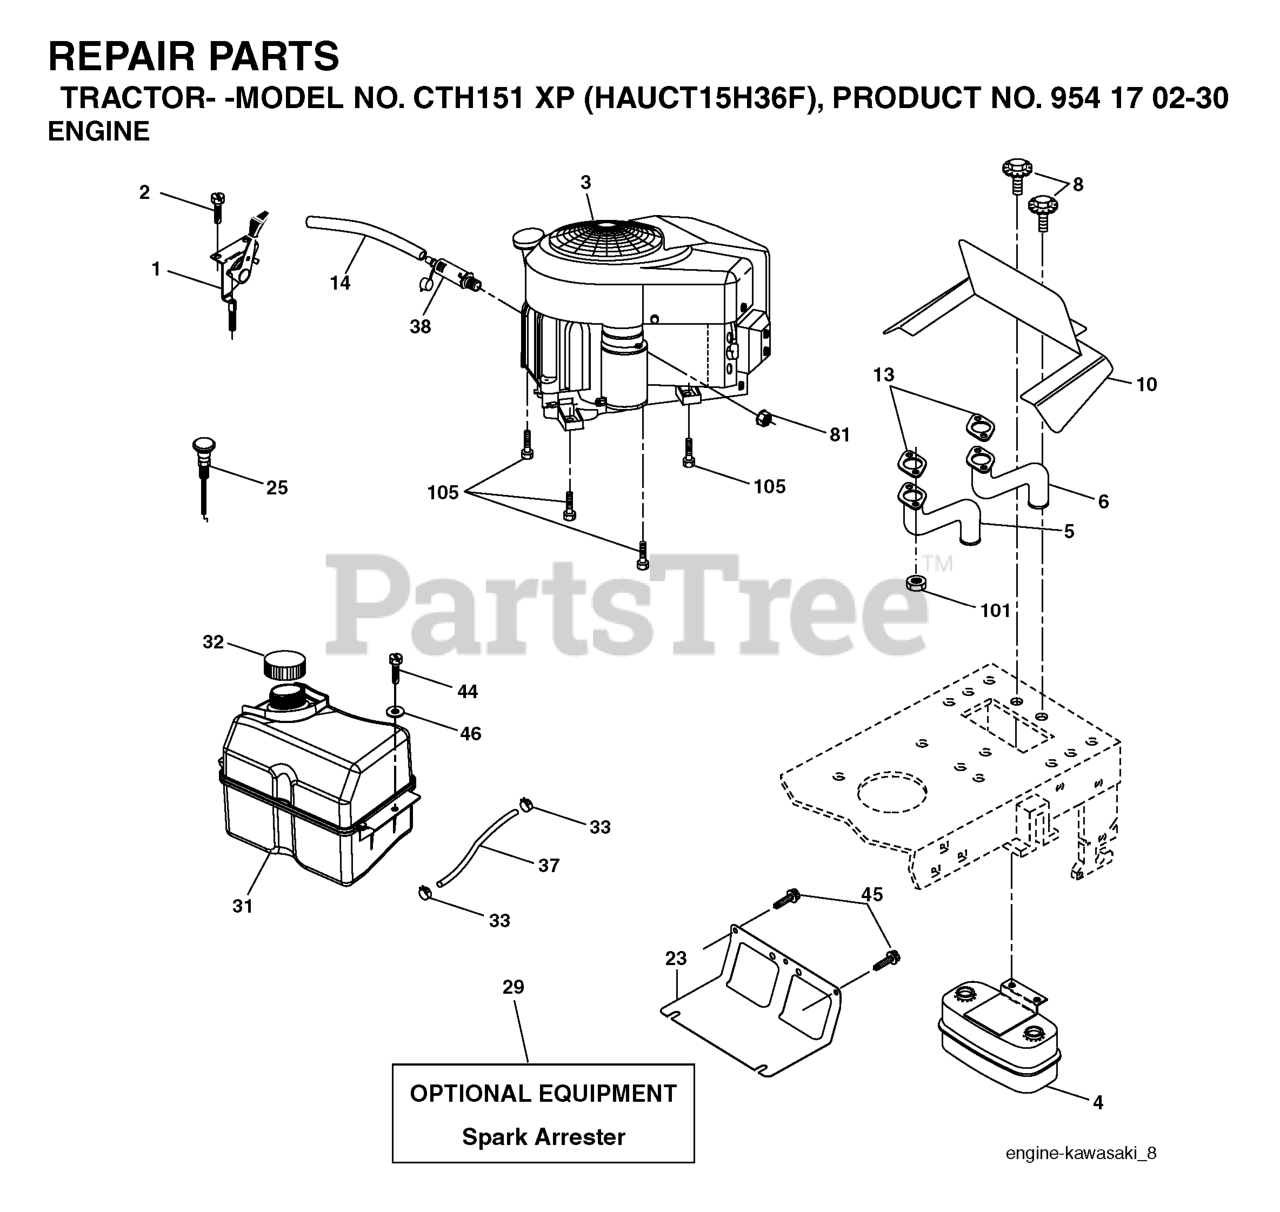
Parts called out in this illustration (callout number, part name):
1	THROTTLE CABLE
2	SCREW
4	MUFFLER.TWIN.CYL.LOW.TONE
5	EXHAUST TUBE LH KAWI
6	EXHAUST TUBE RH KAWI
8	BOLT.5/16-18UNCX3/4 W/SEMS.BLK
10	RP SHIELD HEAT MUFFLER
14	TUBE, DRAIN OIL ASM.
23	SHIELD.BROWNING.DBR.GUARD
25	CONTROL.CHOKE.ERGO.PUSH-IN.BLA
29	KIT.SPARK ARRESTOR 794945 B&S
31	TANK FUEL
32	FUEL CAP
33	HOSE CLAMP
37	LINE.FUEL.20
44	SCREW HEXWSHR 1/4-20X3/4
45	SCREW, 3/8-16X3/4
81	NUT
101	NUT.HEX.FLANGE.TOPLOCK
105	SCREW 3/8-16X1
